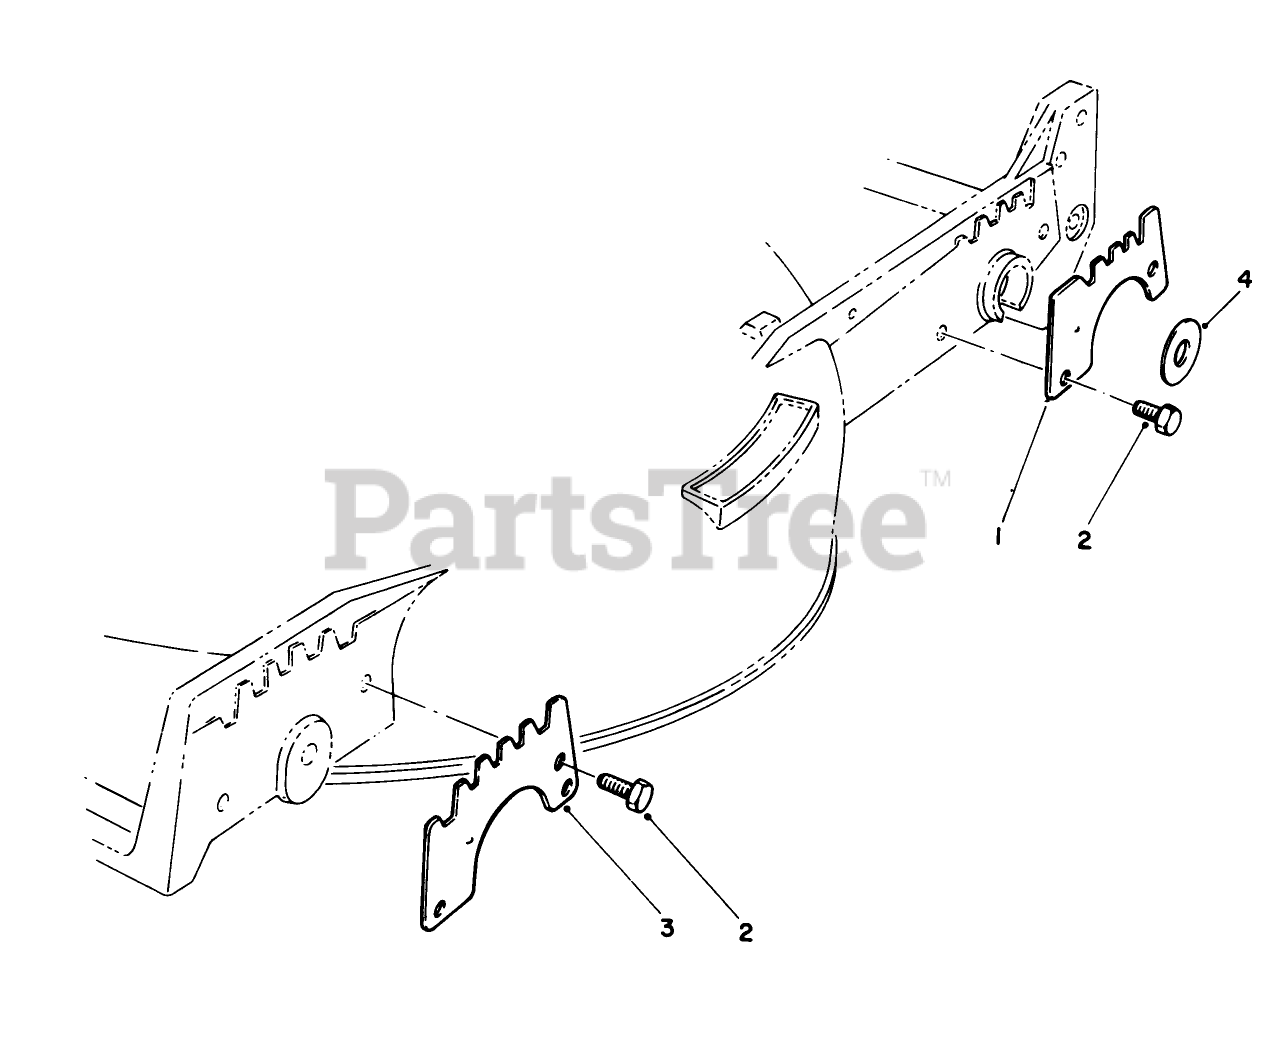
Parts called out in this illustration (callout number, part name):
1	WEAR PLATE,REAR
2	SCREW-HWH
3	WEAR PLATE
4	PIVOT WASHER
